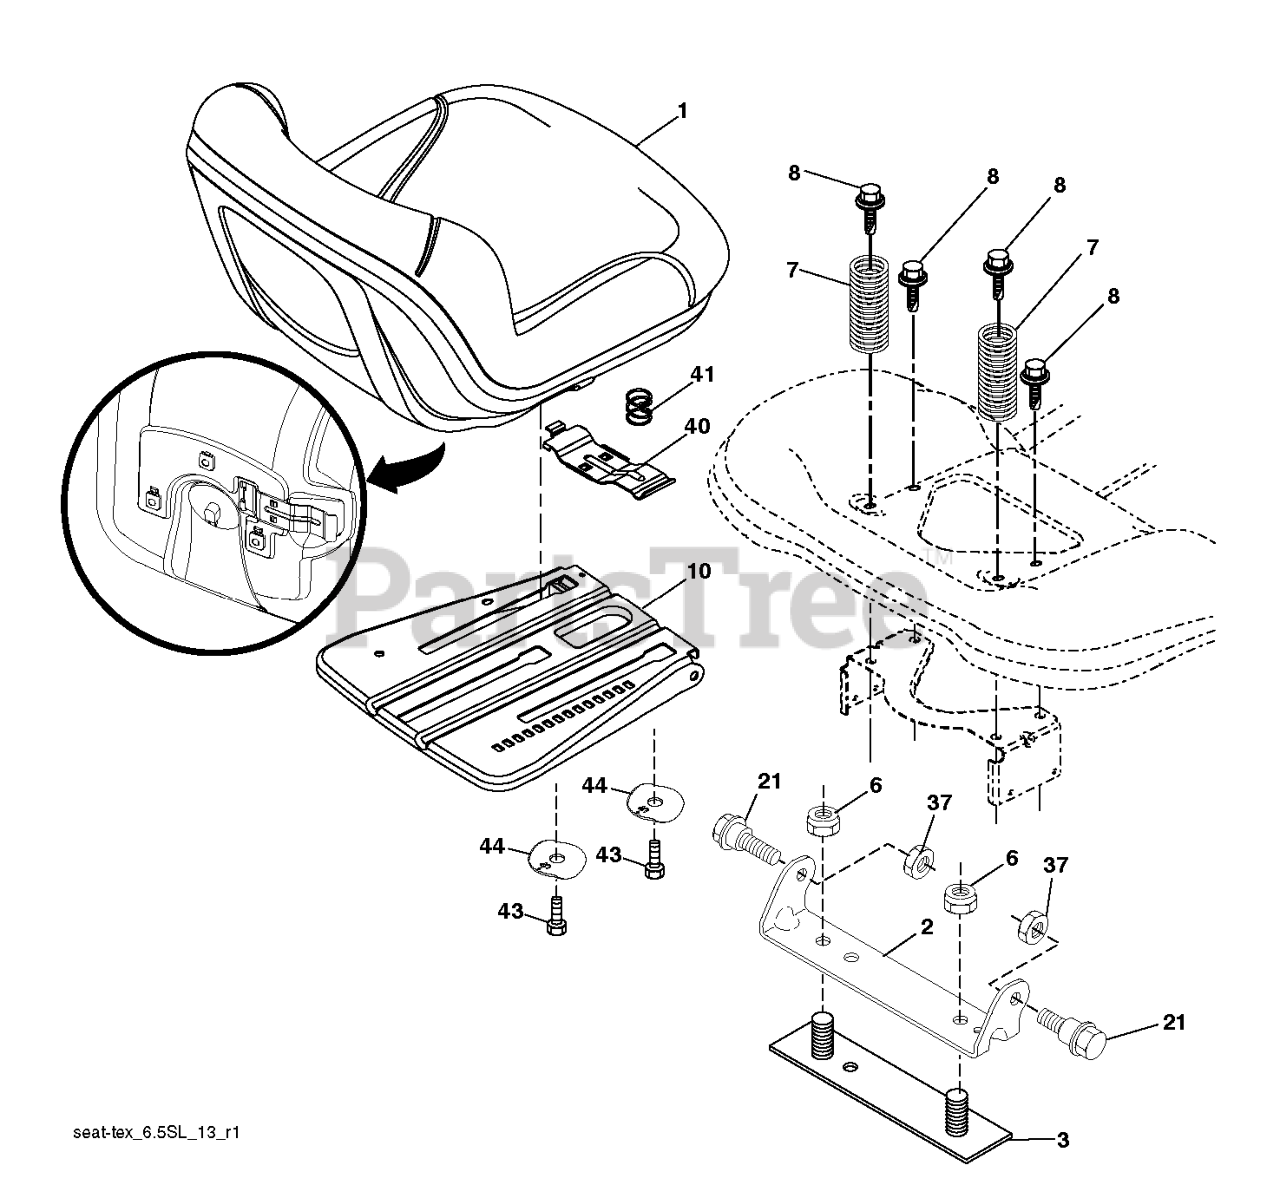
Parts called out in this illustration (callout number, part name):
1	SEAT.TH110.HUSQ.TEX.GREY
2	BRKT.PIVOT.FENDER
3	STRAP
6	NUT
7	SPRING.COMPRESSION.SEAT.BLACK
8	BOLT.5/16-18UNCX3/4 W/SEMS.BLK
10	PLATE.PNT.SEAT.SLIDE.3PT.EDIP
21	BOLT.5/16-18X5/8.SHOULDER
37	NUT.71038.31-18.HEX.NYLOCK
40	HANDLE.SLIDE.SEAT.TEX.BLACK
41	SPRING.LATCH.SEAT.TEX
44	WASHER.WINGED.3/8ID.1.5OD
